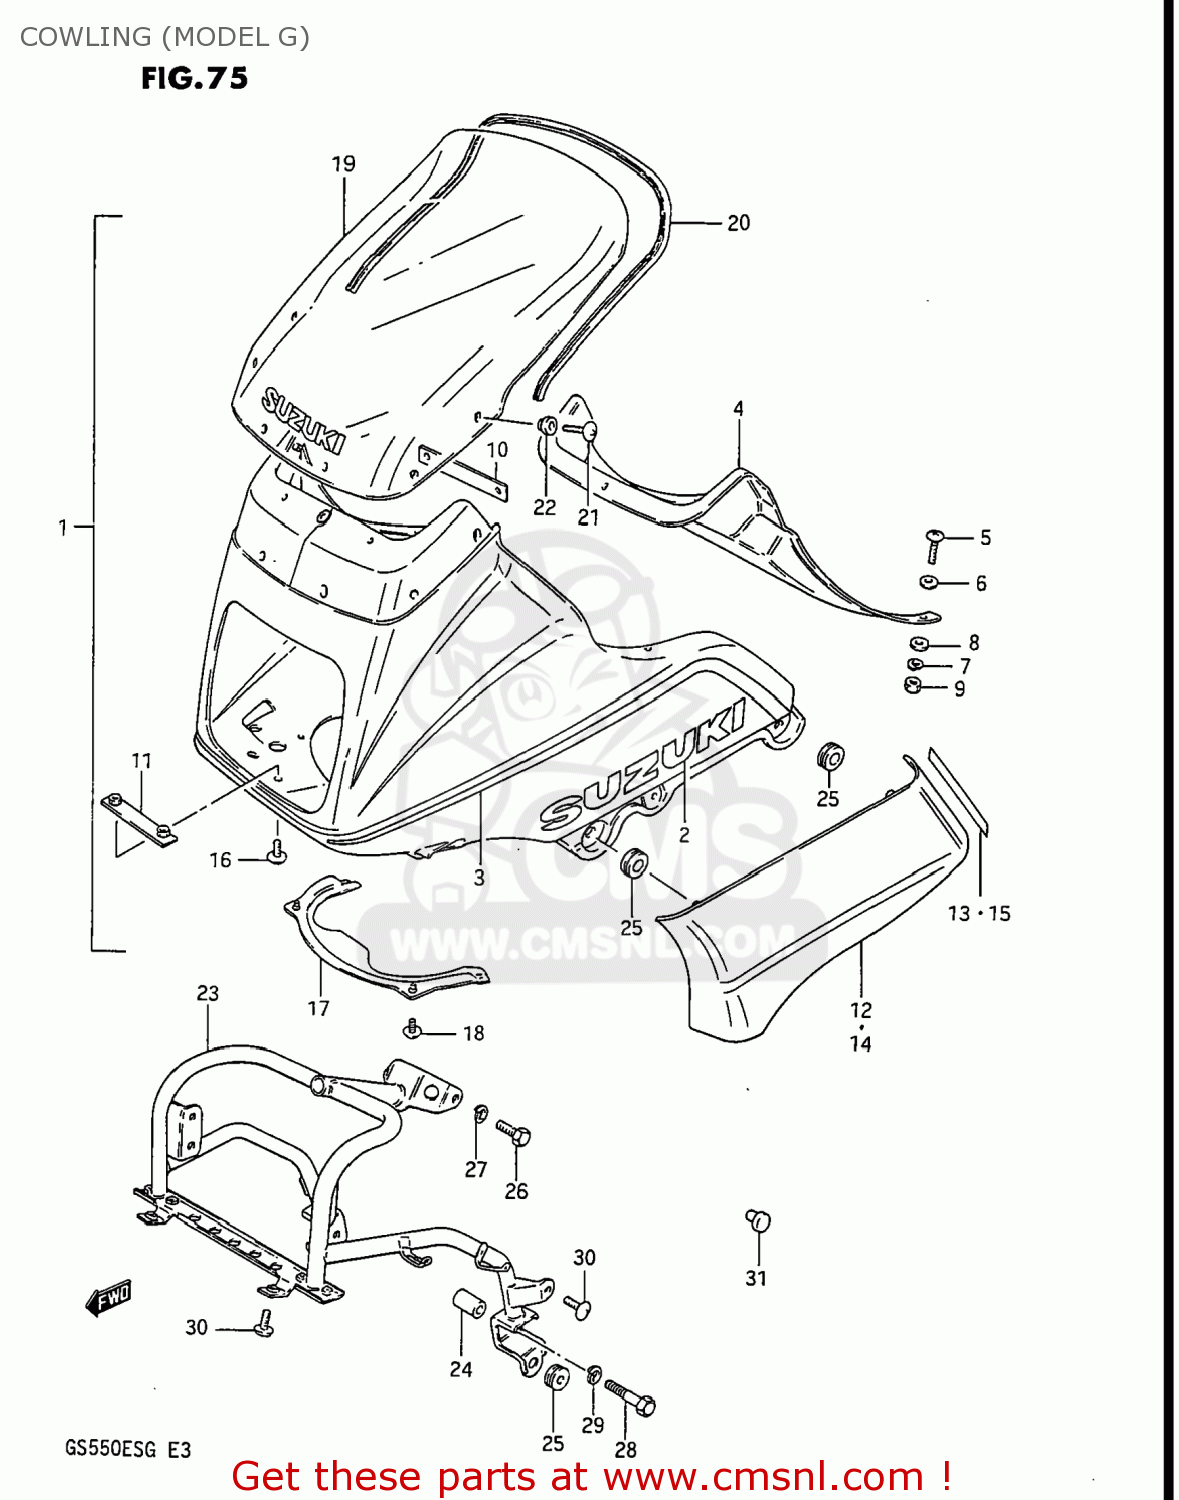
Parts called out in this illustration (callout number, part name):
1	BODY ASSEMBLY,COWLING
2	EMBLEM
3	TAPE SET
4	PANEL,COWLING,UPPER
5	SCREW
6	WASHER,5MM
7	WASHER,LOCK
8	WASHER,5MM
9	NUT ,5MM
10	BRACKET,COWLING,UPPER
11	BRACKET,COWLING,LOWER
12	COVER,COWLING,RIGHT
13	TAPE SET,COWLING
14	COVER,COWLING,LEFT
15	TAPE SET,COWLING
16	SCREW
17	COVER,COWLING,LOWER
18	SCREW
19	WINDOW,COWLING
20	MOLDING,LOWER
21	SCREW
22	CUSHION
23	BRACE,COWLING
24	SPACER (8.2X12.5X23.5)
25	CUSHION
26	BOLT
27	WASHER,LOCK,8.
28	BOLT
29	WASHER,LOCK,8.
30	SCREW 6X12
31	PLUG
